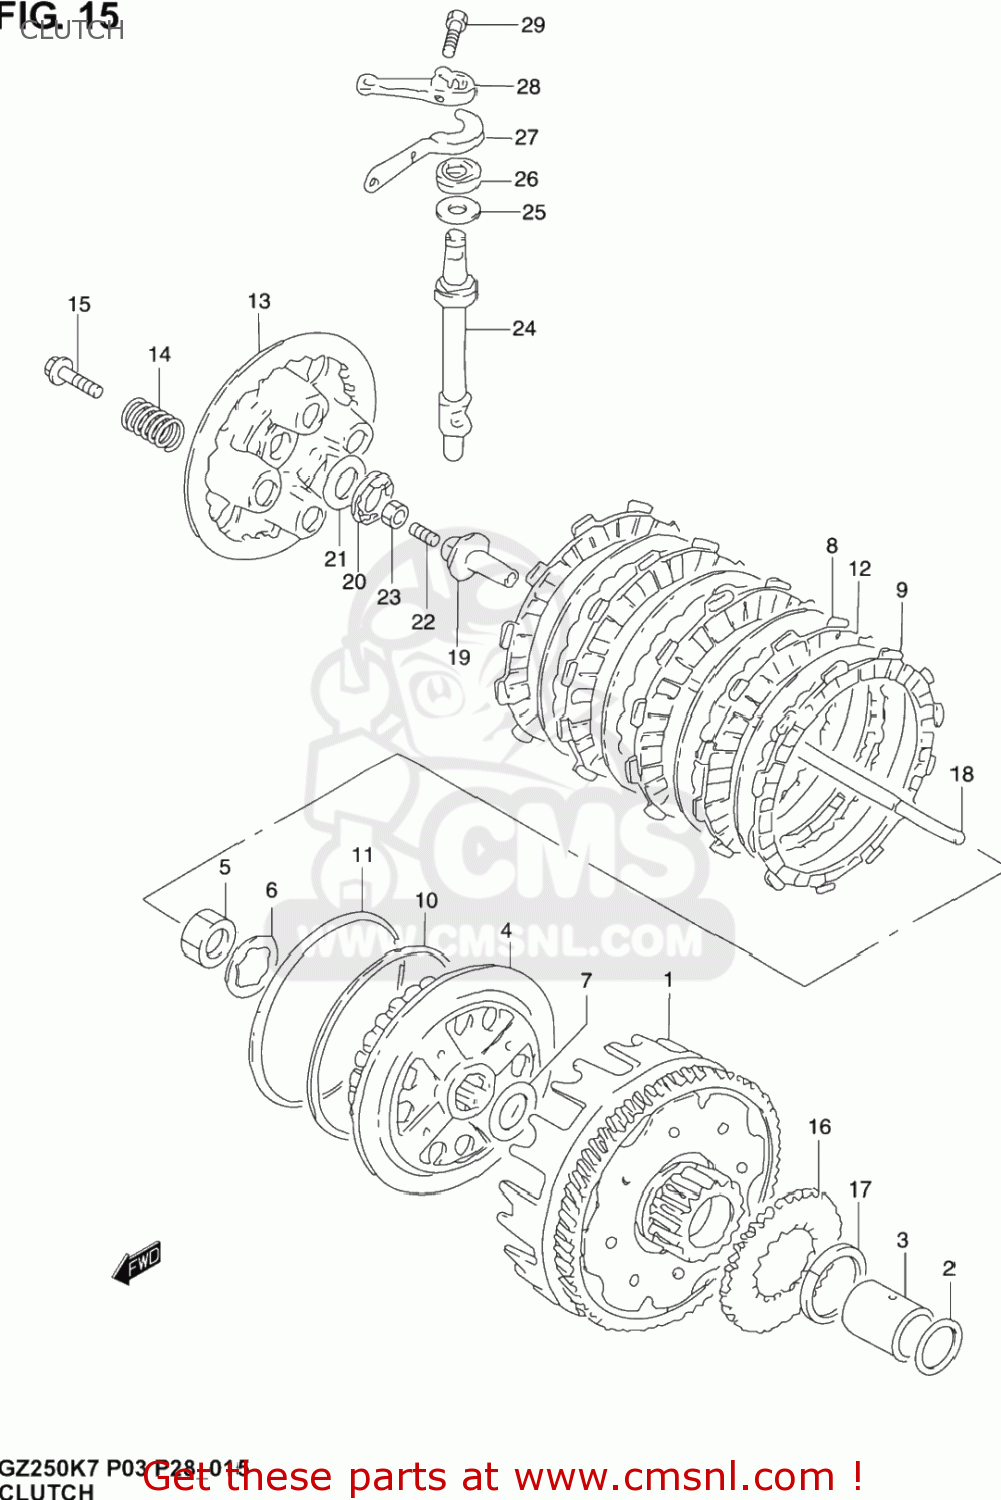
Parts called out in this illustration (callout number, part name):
1	GEAR ASSY,PRI DRIVEN
2	WASHER
3	SPACER(22X28X37.5)
4	HUB,CLUTCH SLEEVE
5	NUT
6	WASHER,LOCK
7	WASHER
8	PLATE,CLUTCH DRIVE (NAS)
9	PLATE,CLUTCH DRIVE(T:3.5) (NAS)
10	SEAT,WAVE WASHER(T:1.4)
11	WASHER
12	PLATE,CLUTCH DRIVEN(T:1.6) (NAS)
13	DISC,CLUTCH PRESSURE
14	SPRING,CLUTCH
15	BOLT(6X20)
16	GEAR,ENG OIL PUMP(NT:38)
17	CIRCLIP
18	ROD,CLUTCH PUSH
19	PIECE,CLUTCH PUSH
20	BEARING(15X28X2)
21	WASHER(15.5X28X1)
22	SCREW(6X25)
23	NUT
24	CAMSHAFT,CLUTCH RELEASE
25	WASHER(14.5X22X1)
26	OIL SEAL
27	PLATE,CLUTCH RRS CAMSHAFT SEAL
28	ARM,CLUTCH RELEASE
29	BOLT
